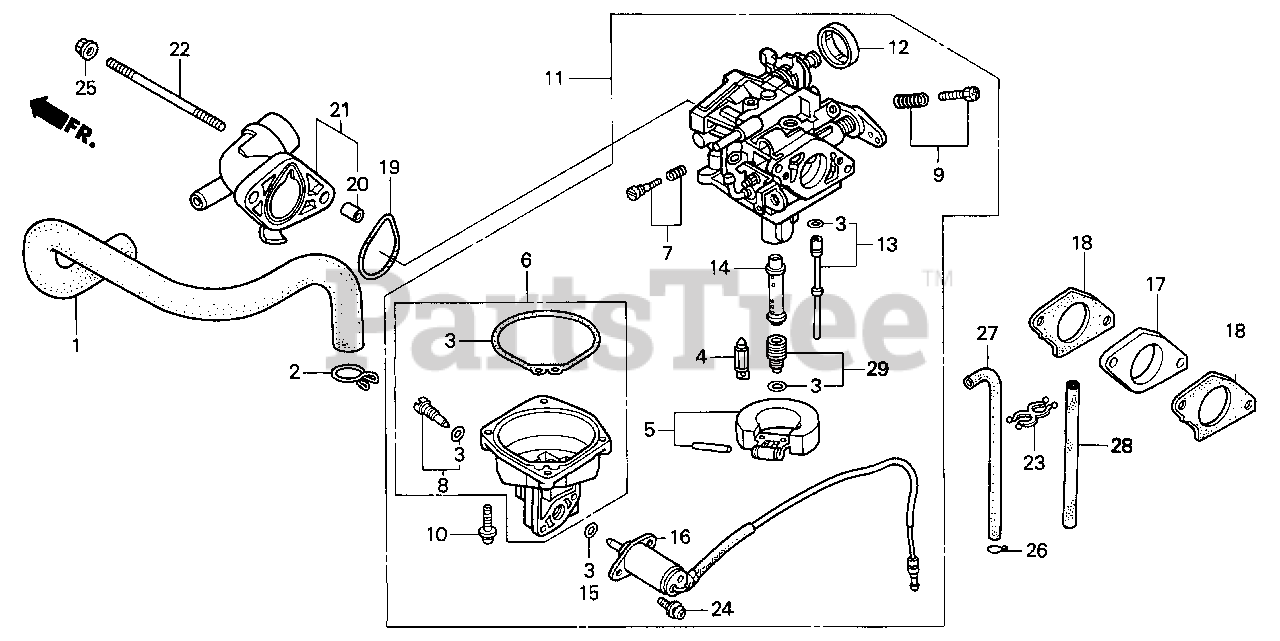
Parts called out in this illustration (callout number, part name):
1	TUBE, BREATHER
2	CLIP, BREATHER TUBE
3	GASKET SET
4	VALVE SET, FLOAT
5	FLOAT SET
6	CHAMBER SET, FLOAT
7	SCREW SET
8	SCREW SET, DRAIN
9	SCREW SET
10	SCREW-WASHER
11	CARBURETOR ASSY.
12	CAP, CHOKE LEVER DUST
13	JET SET (#48)
14	NOZZLE, MAIN
17	INSULATOR, CARBURETOR
18	GASKET, CARBURETOR
19	GASKET, AIR CLEANER
20	COLLAR A, AIR CLEANER
21	ELBOW, AIR CLEANER
22	BOLT, STUD (6X108)
23	CLIP, WIRE HARNESS
25	NUT, FLANGE (6MM)
26	CLIP, TUBE (B8)
27	BULK HOSE, VACUUM (3.5X1000) (3.5X600)
28	BULK HOSE, VACUUM (4.5X1000) (4.5X450)
29	JET, MAIN (#90)
29	JET SET (#92)
29	JET SET (#95)
